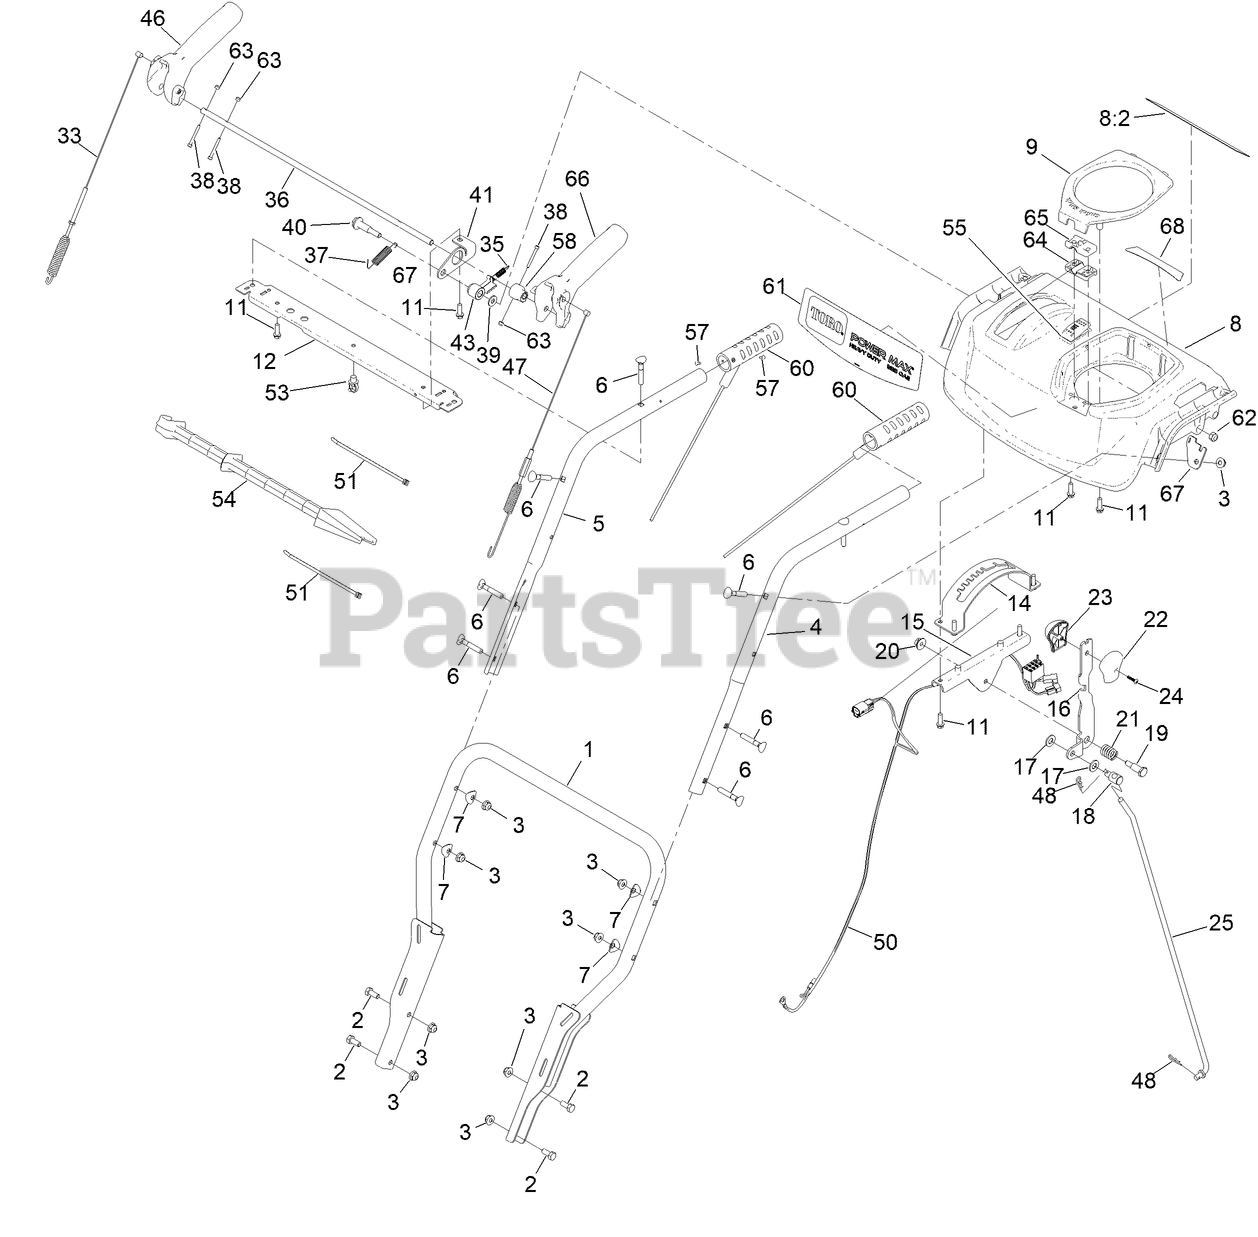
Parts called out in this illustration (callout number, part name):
1	HANDLE-LOWER
2	SCREW-HH
3	NUT-HF
4	HANDLE-UPPER, LH
5	HANDLE-UPPER, RH
6	SCREW-HANDLE
7	WASHER-CUP
8	CONTROL PANEL ASSEMBLY
8:2	DECAL-SAFETY
9	COVER-QUICKSTICK
11	SCREW-PLASTITE, HWH
12	BRACE-CONSOLE
14	GATE-SHIFT
15	BRACKET-SHIFT
16	SELECTOR-SPEED
17	WASHER-FLAT
18	TRUNNION-ROD
19	SCREW-SHOULDER, HH
20	NUT-HF
21	SPRING-COMPRESSION
22	KNOB-SHIFT, LH
23	KNOB-SHIFT, RH
24	SCREW-PPH
25	ROD-SHIFT
33	CABLE-AUGER
35	SPRING-LOCKOUT, HANDLE
36	ROD-LOCKOUT
37	SPRING-RETURN, LEVER
38	SCREW-HSH,SPL
39	WASHER-FLAT
40	SCREW-SHOULDER
41	BRACKET-INTERLOCK
43	LATCH, LOCKOUT
46	LEVER-CONTROL
47	CABLE-TRACTION
48	PIN-HAIR
50	HARNESS-WIRE, LED AND HAND WARMERS
51	TIE-CABLE
53	CLIP-TIE
54	STICK-CLEANOUT
55	SWITCH-ROCKER, ON-NONE-OFF (HEATER)
57	RIVET-POP
58	CAM-LOCKOUT
60	GRIP-HEATED
61	DECAL-CONSOLE
62	NUT-HEX
63	NUT-LOCK ROHS
64	SUPPORT-ROD, LOWER
65	SUPPORT-ROD, UPPER
66	LEVER-CONTROL
67	PLATE-SPRING
68	DECAL - QUICK STICK
